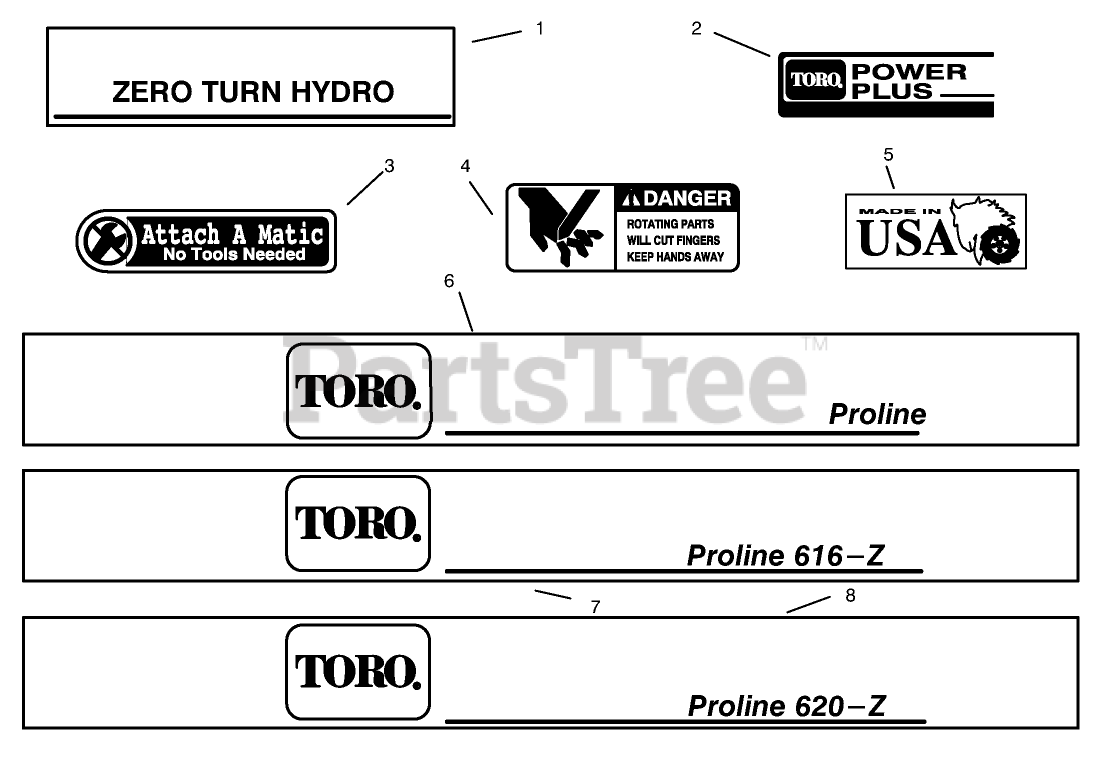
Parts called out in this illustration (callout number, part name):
1	DECAL-ZERO TURN HYD
2	DECAL POWER PLUS 16
3	DECAL-ATTACH A-MATIC
4	DECAL - DANGER
5	DECAL - USA
6	DECAL-TORO REAR
7	DECAL - TORO 616-Z
8	DECAL - TORO 620-Z
